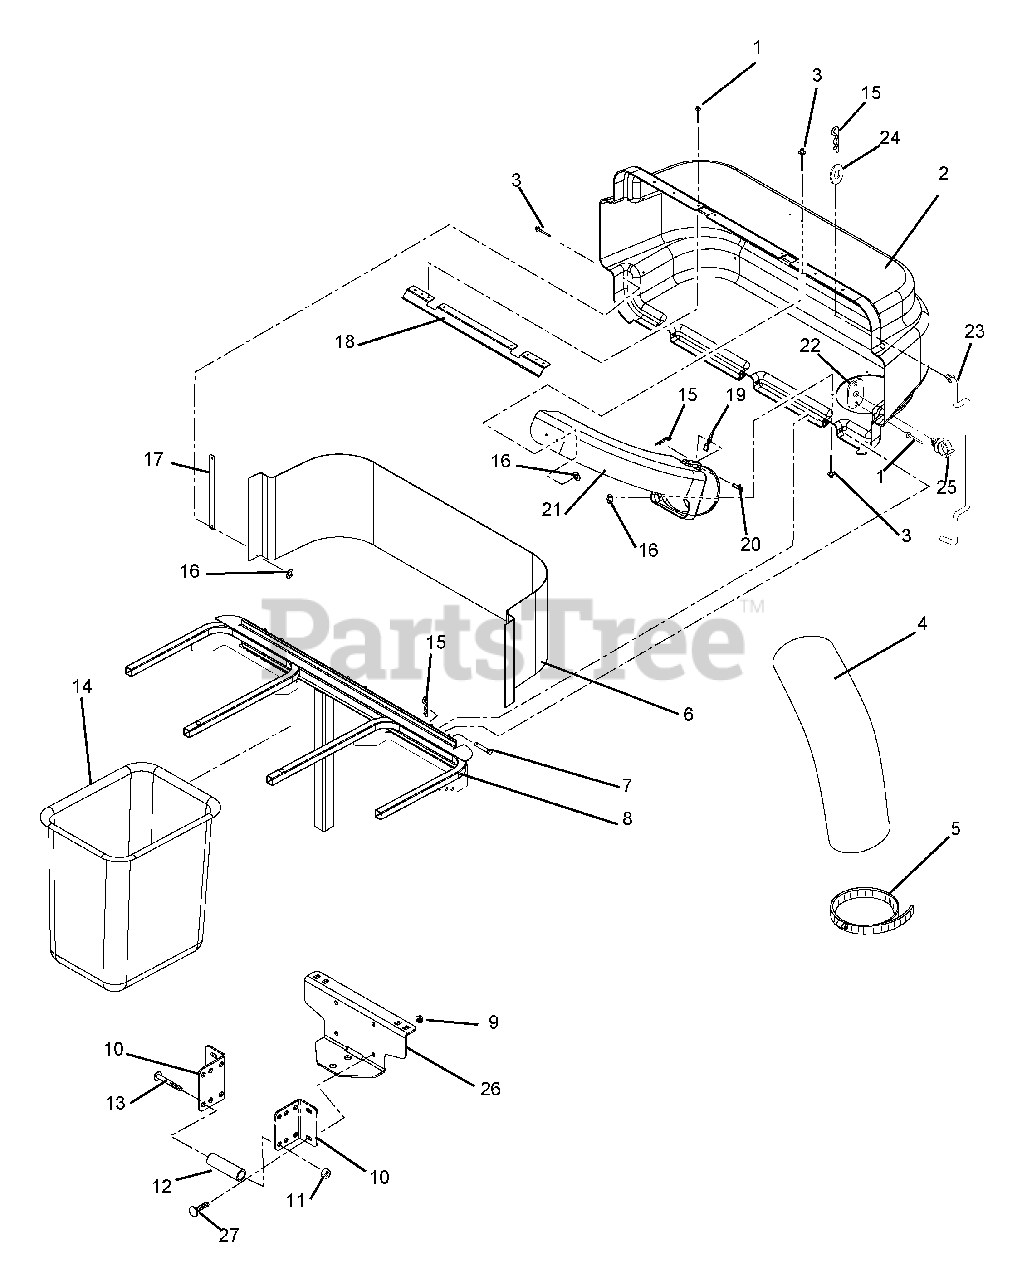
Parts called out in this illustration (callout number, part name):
1	RVT-POP .187X.402 DOME ST
2	BAGGER COVER W/DECAL
3	RVT-POP .187X.375
4	HOSE 7 X 45
5	CLAMP, 7" TOOL-LESS HOSE
6	SCREEN, BAGGER
7	PIN-CLEV .371X3.25 YWZC
8	WMT,BAGGER FRAME
9	@NUT-LK-TOP-FLG .38-16 YWZC
10	BKT,BAGGER MOUNT
11	@NUT-LK-TOP-FLG .50-13 YWZC
12	SPACER, PIVOT .500X.750X1.805
13	@BLT-HEX .50-13X3.00 GR5 YWZC
14	GRASS BAGGER BASKET
15	PIN-HAIR, ENDRIES #25 YWZC
16	@WSHR-FL-STL.219X.50X.049 YWZC
17	STRAP,COVER
18	LATCH,COVER
19	INDICATOR, FLOW
20	PIN-CLEV .309 X 1.625 YWZC
21	BOOT,UPPER
22	PLATE, ROD CLIP
23	PROP-ROD, BAGGER
24	@WSHR-FL-STL.406X.812X.065 YWZ
25	CLIP-.38
26	ASSM, TRAILER HITCH
27	@BLT-RDHDSQNK .38-16X.75 G5YZ
